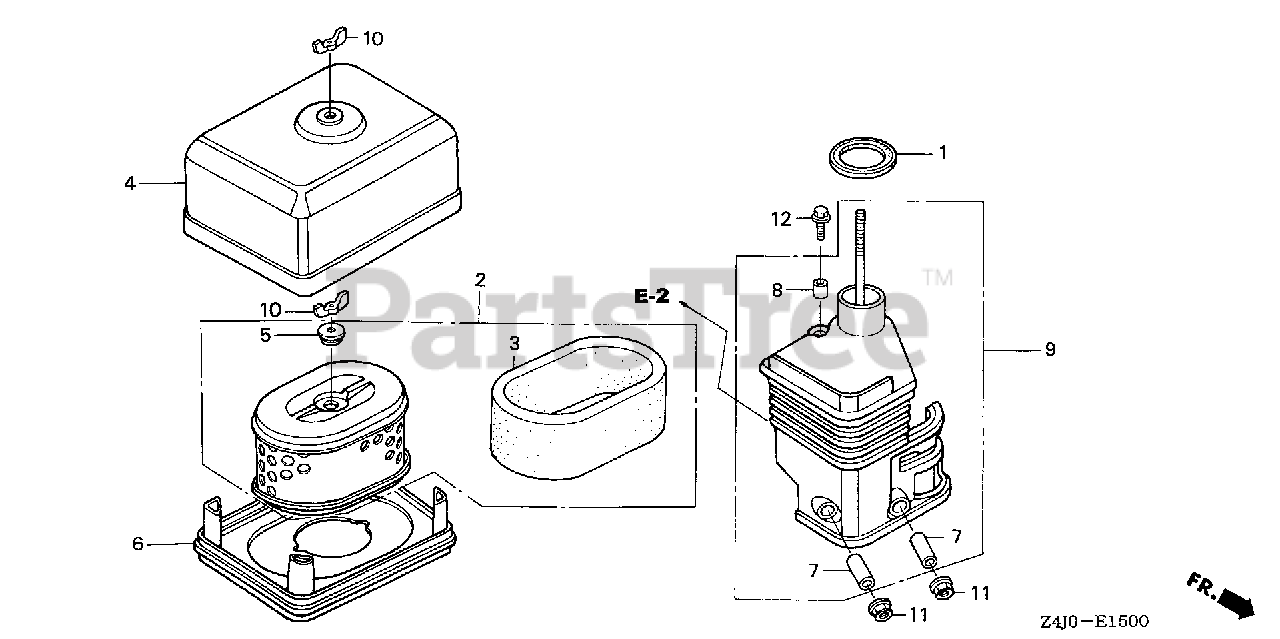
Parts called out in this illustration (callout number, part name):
1	GASKET, ELBOW
2	ELEMENT, AIR CLEANER (DUAL) Use up to Engine SN 2115700.
2	ELEMENT, AIR CLEANER (DUAL)
3	FILTER (OUTER)
4	COVER, AIR CLEANER (DUAL)
5	GROMMET, AIR CLEANER
6	NOSE, MUFFLER
7	COLLAR, AIR CLEANER Use from Engine SN 1786085.
8	COLLAR B, AIR CLEANER
9	ELBOW, AIR CLEANER
10	WINGNUT, TOOL BOX SETTING
11	NUT, FLANGE (6MM)
12	BOLT, FLANGE (6X20)
